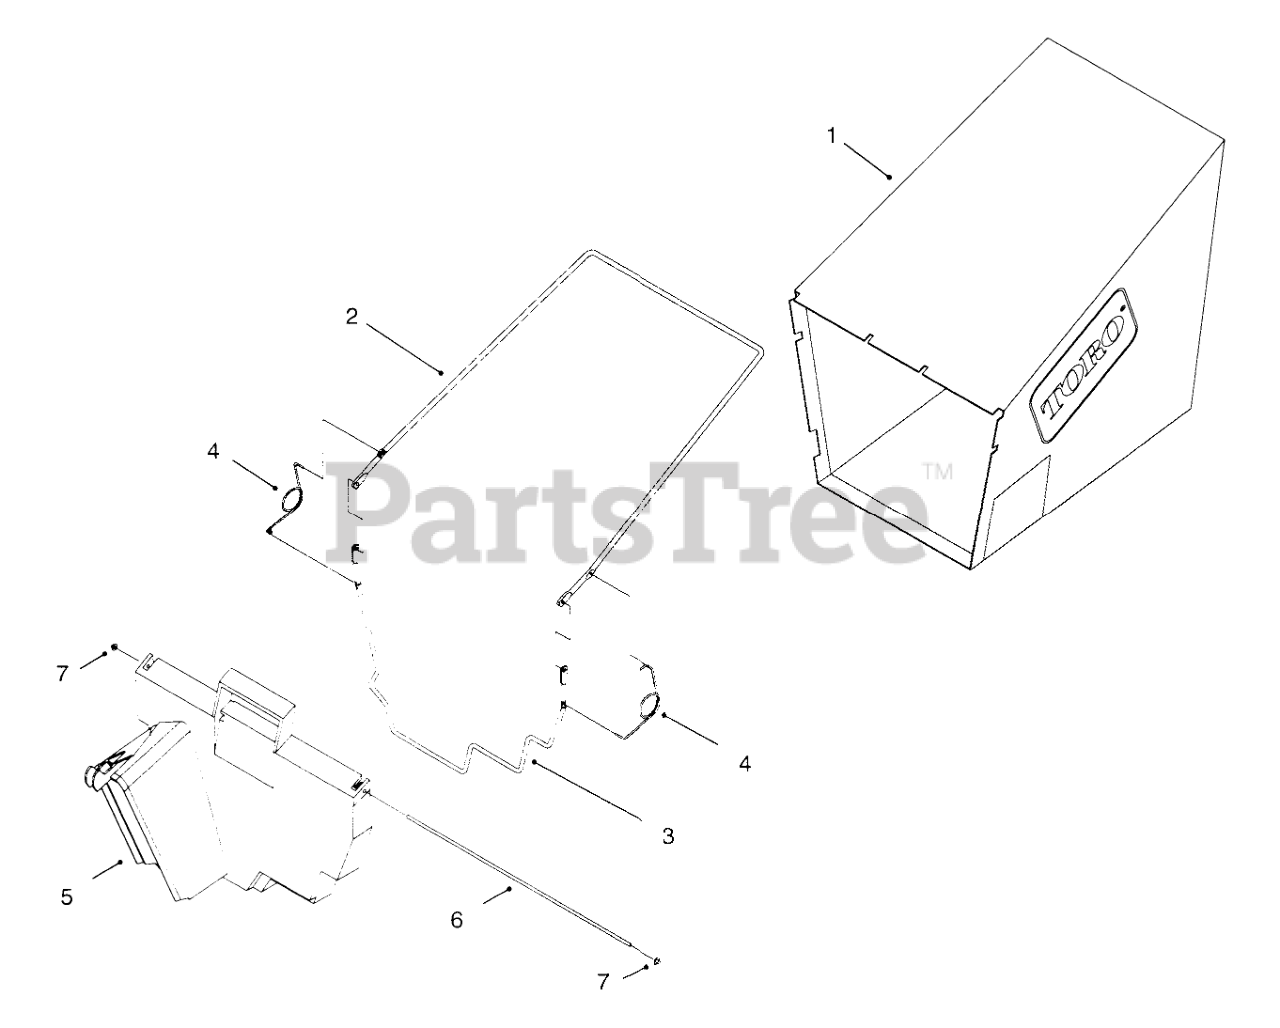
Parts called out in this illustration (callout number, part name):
1	BAG-GRASS
2	FRAME-UPPER BAG
3	FRAME-LOWER BAG
4	SPRING
5	DOOR-BAG
6	HINGE-BAG DOOR
7	NUT-PUSH
